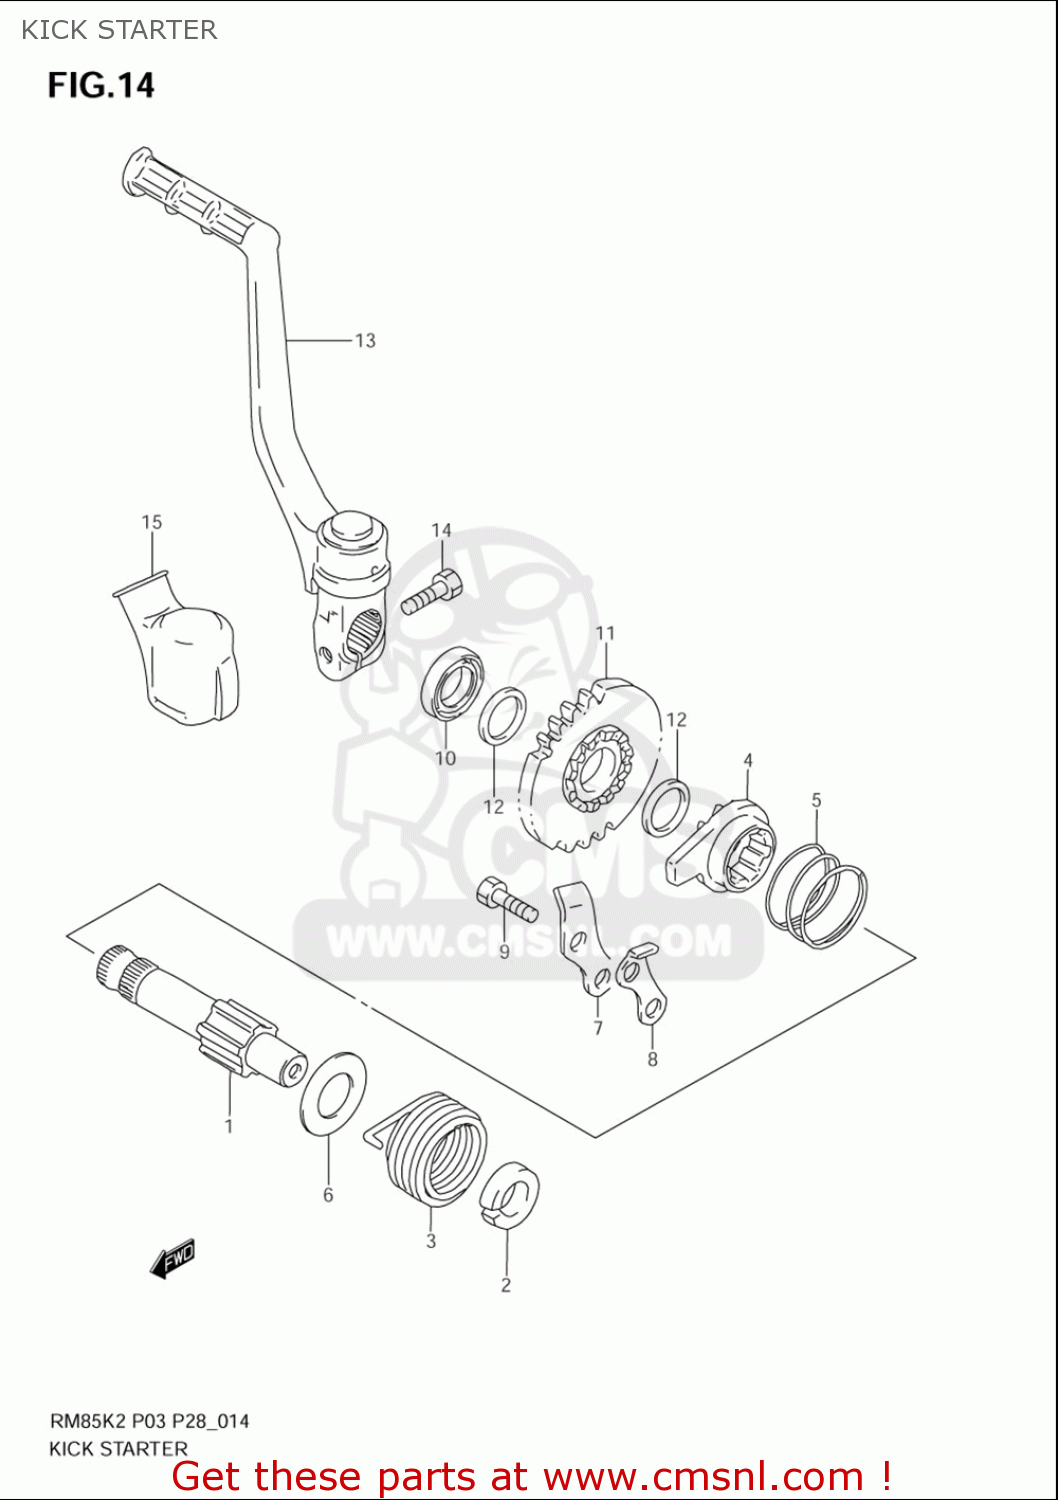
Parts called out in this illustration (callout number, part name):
1	SHAFT,KICK STARTER
2	GUIDE,SPRING
3	SPRING
4	STARTER,KICK
5	SPRING
6	WASHER
7	GUIDE,KICK STARTER
8	STOPPER,KICK STARTER
9	BOLT
10	SEAL,OIL(14X24X6)
11	GEAR,KICK STARTER DRIVE(NT:26)
12	SHIM(14X20X1)
13	LEVER ASSY,KICK STARTER
14	BOLT
15	COVER,KICK LEVER JOINT
